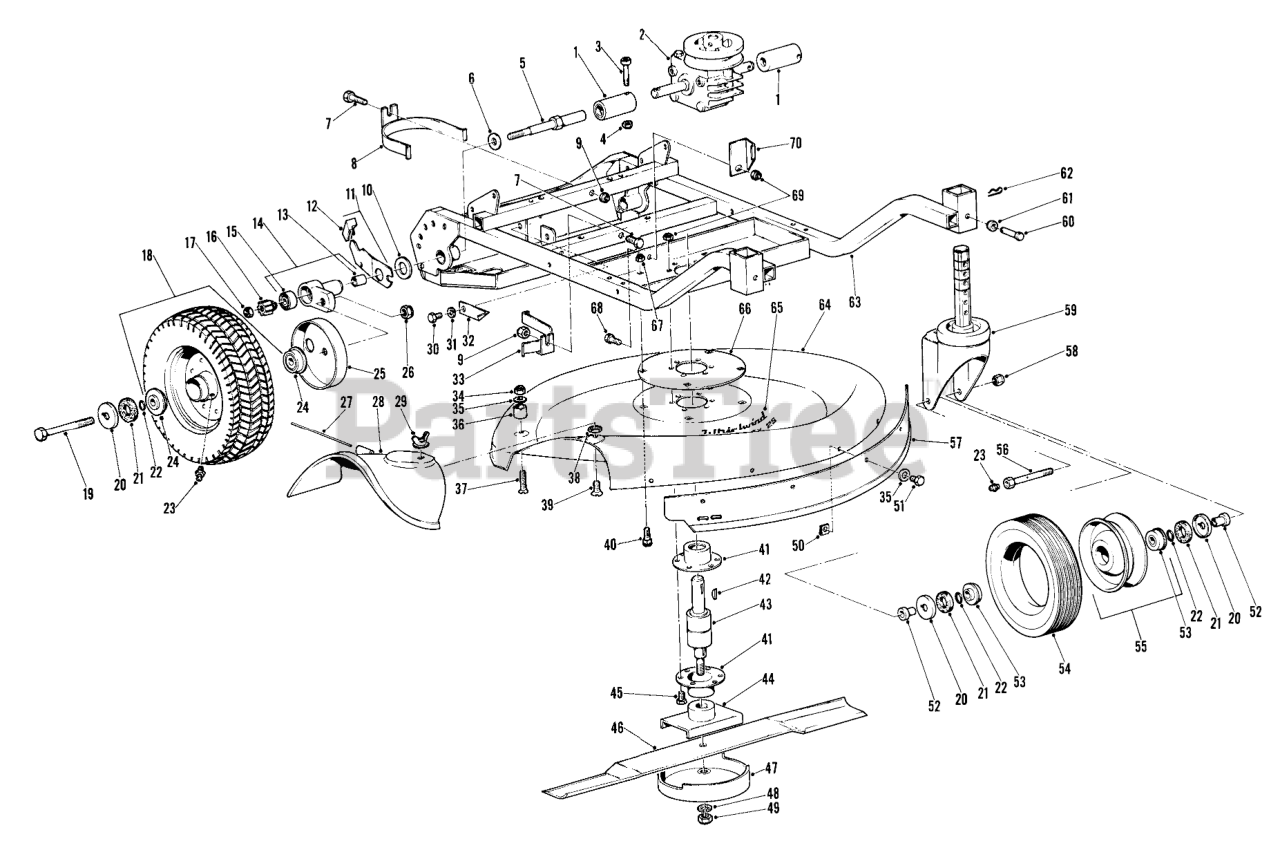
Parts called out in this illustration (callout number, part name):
1	Clutch Assy.
2	Transmission Assembly
3	DRIVE SCREW
4	NUT-LOCK, NI
5	DRIVE SPINDLE
6	Washer
7	SCREW-HH
8	Belt Retainer W.A.
9	NUT-LOCK, NI
10	WASHER
11	RH SPRING ARM ASM
12	ARM KNOB
13	BUSHING
14	Pivot Arm
15	.375 RPP BALL BEARING
16	Pinion Kit
17	NUT-HJ
18	REAR WHEEL & TIRE ASM
19	SCREW-HH
20	SLINGER
21	Washer
22	O-RING
23	FITTING-GREASE
24	BEARING
25	Wheel Cover
26	NUT-LOCK, NI
27	Hinge Pin
28	DEFLECTOR
29	Wing Nut
30	SCREW-HH
31	WASHER-LOCK
32	Retainer
33	Belt Retainer W.A.
34	NUT-HEX
35	WASHER-FLAT
36	Spacer
37	Screw
38	PAL NUT
39	5/16-18X7/8 FLT HD MS
40	BOLT-CARR
41	BEARING HOUSING
42	KEY-WOODRUFF
43	Bearing Spindle
44	Retainer
45	SCREW-HH
46	Blade
48	WASHER-LOCK
49	NUT-HEX
50	SPEED NUT
51	SCREW-HH
52	Spacer
53	BEARING-BALL
54	1.75-8 SEMIPNEU TIRE
55	Wheel W.A. w/Ref. No. 53
56	Bolt
57	Cover
58	NUT-LOCK, NI
59	Caster
61	Grommet
62	PIN-COTTER
63	Frame
64	Housing
65	Decal
66	Plate
67	NUT-LOCK, NI
68	SCREW-HH
69	NUT-LOCK, NI
70	Belt Retainer
